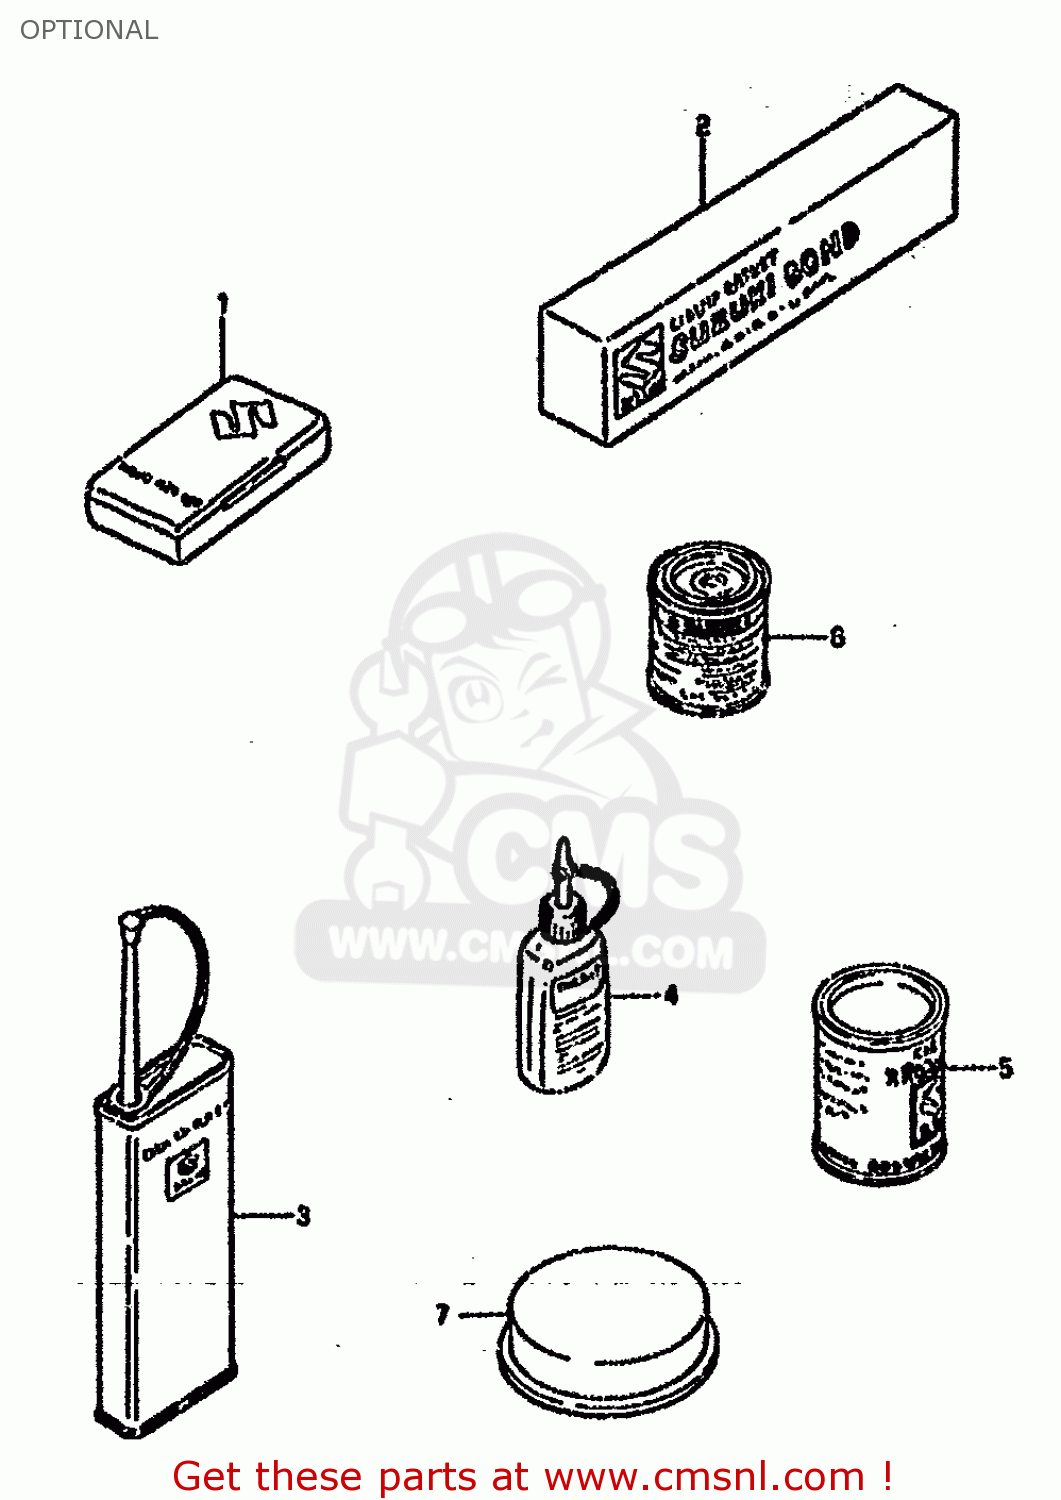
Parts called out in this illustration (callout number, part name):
1	TUBE REPARING TOOL
2	BOND 1104
3	THREAD LOCK NO.1401 CLEAR 200G
4	THREAD LOCK NO
5	GREASE(C)EP2 LITHIUM 150G
6	PAINT,BLACK
7	GREASE,PBC FOR BRK PAD 20G
